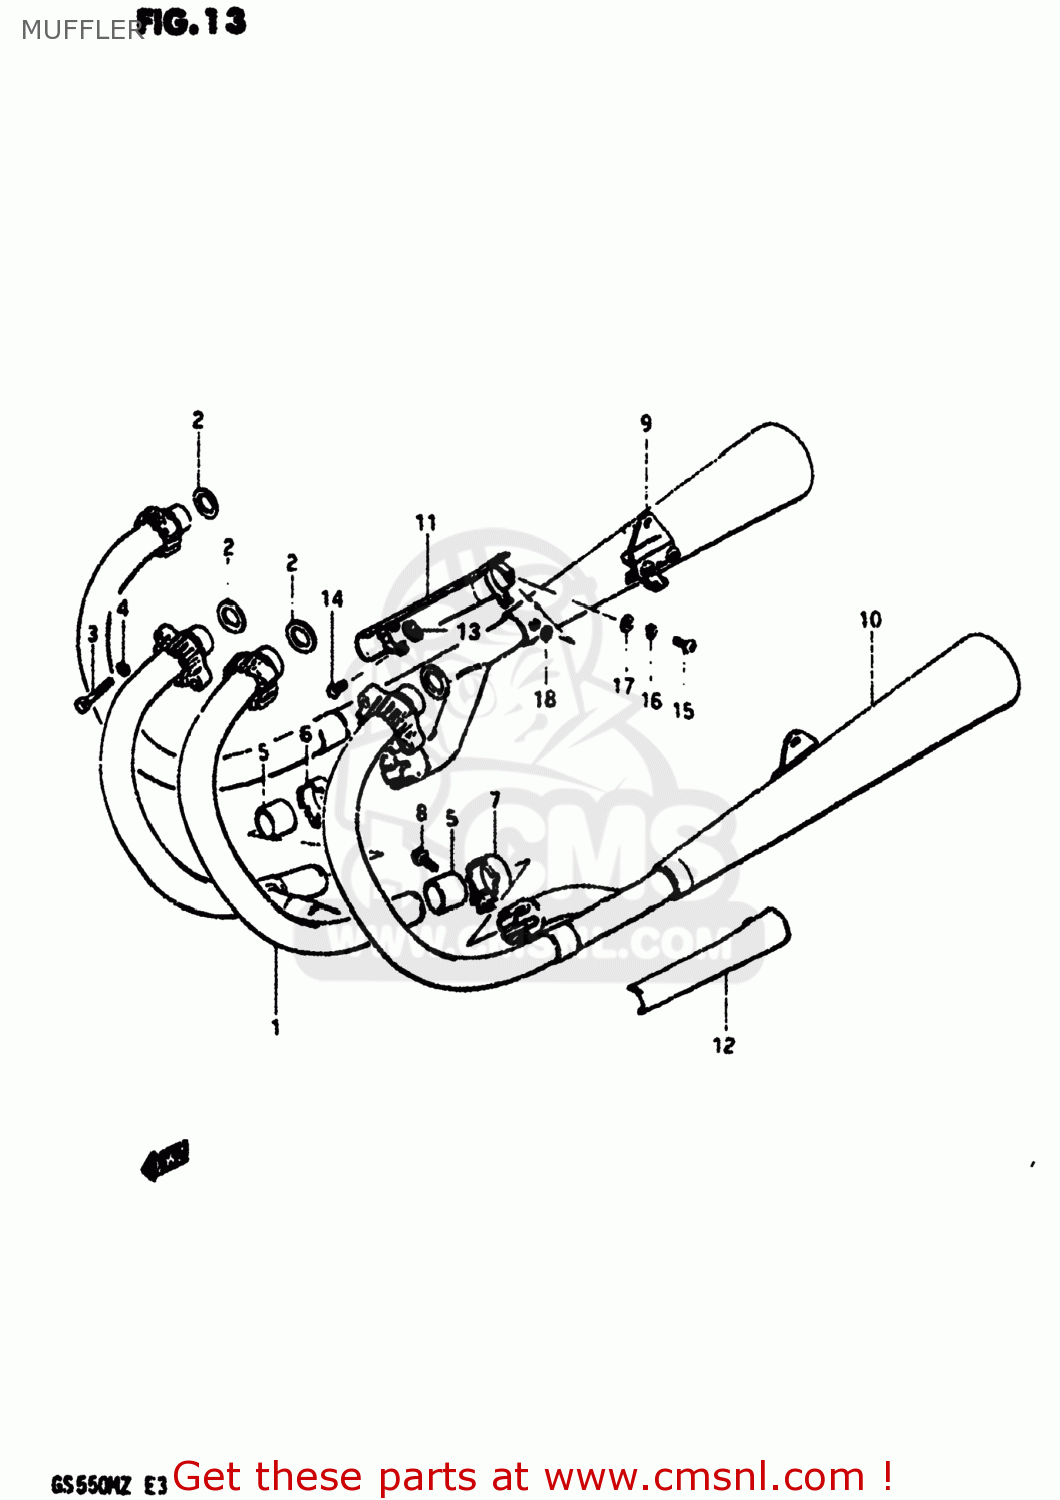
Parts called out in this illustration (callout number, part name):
1	PIPE,EXHAUST,CENTER
2	GASKET,EXHAUST PIPE (NAS)
3	BOLT
4	LOCK WASHER
5	CONNECTOR,MUFFLER
6	CLAMP,MUFFLER CONNECTOR
7	CLAMP,MUFFLER CONNECTOR
8	BOLT
9	MUFFLER ASSEMBLY
10	MUFFLER ASSEMBLY
11	COVER,MUFFLER,RIGHT
12	COVER,MUFFLER,LEFT
13	CLAMP,MUFFLER COVER
14	SCREW 5X20
15	SCREW 6X12
16	LOCK WASHER
17	WASHER
18	GASKET 6.2X12X1.5 (MCA)
